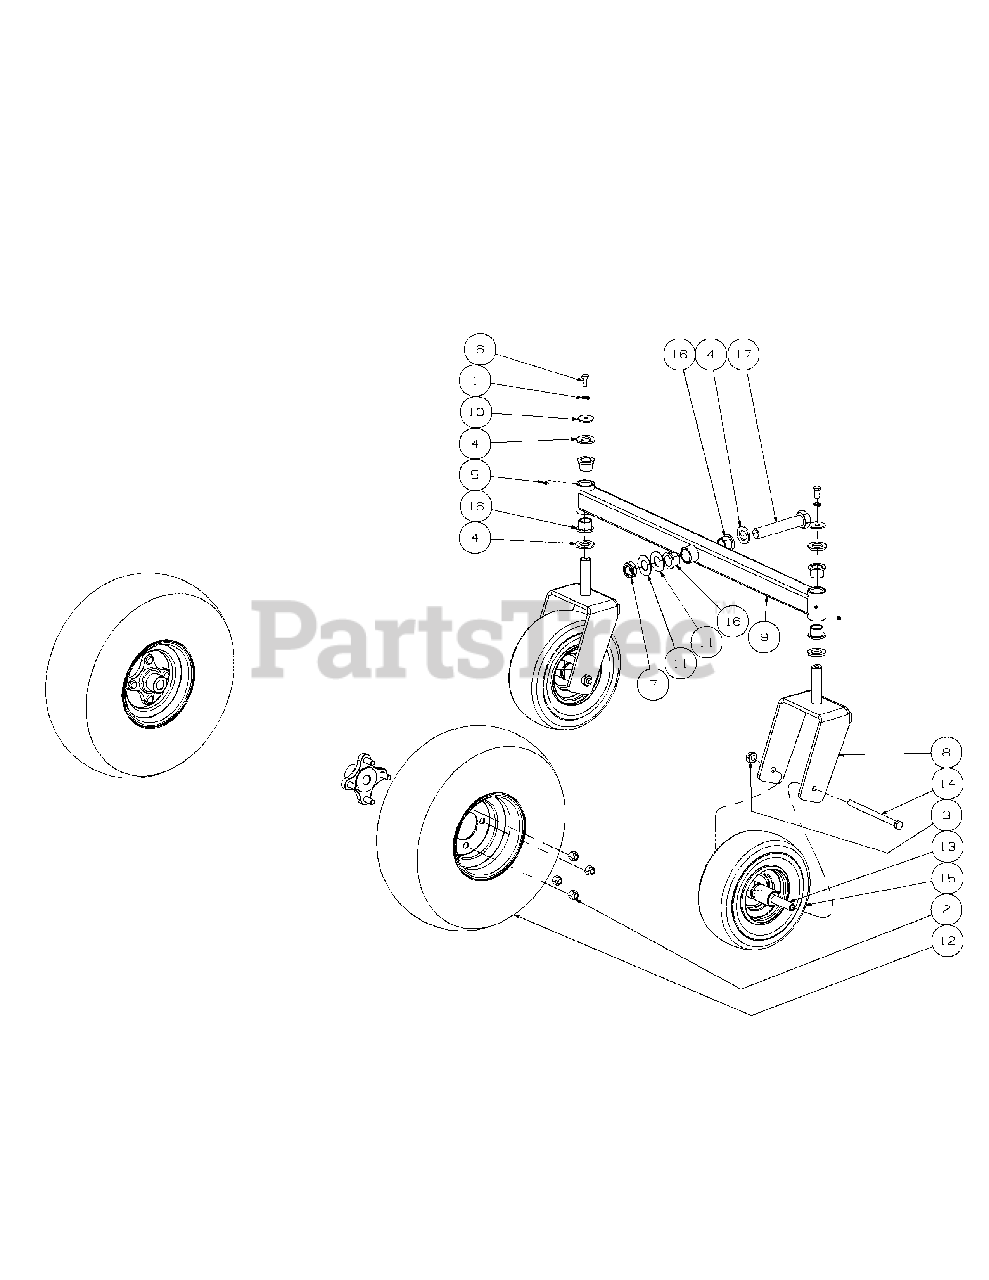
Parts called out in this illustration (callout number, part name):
1	Lock Washer, 3/8 Zinc
2	Lug Nut, 1/2-20
3	Lock Nut, Nylon Insert, 1/2-20
4	Washer Special
5	Grease Fitting, 1/4-28 x 3/16
6	Hex Cap Screw, 3/8-16 x .88
7	Nut Jam, 1.0-14, Nylon Insert
8	Castor Wheel Mounting Bracket
9	Front Axle Assembly
10	Flat Washer, .390 x 1.5 x .134
11	Flat Washer, 1.00 ID x 2.25 OD x ,075
12	Wheel Assembly, 20 x 8-10 NHS
13	Wheel Spacer
14	Hex Cap Screw, 1/2-20 x 7.50
15	Wheel Assembly 11 x 6.00 - 5, Beige
16	Flange Bearing, 1.001 x 1.25
17	Hex Cap Screw, 1-14 x 5.5
